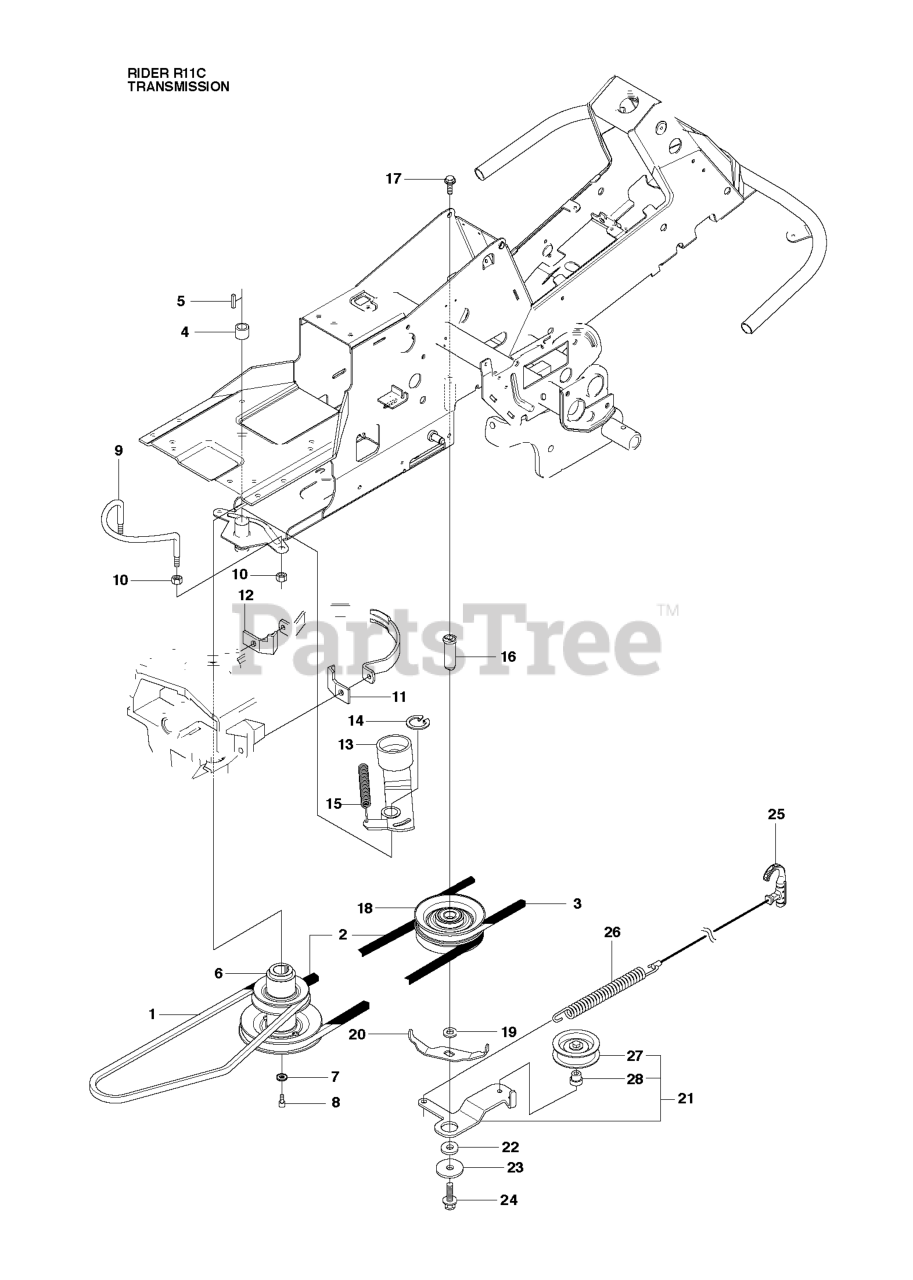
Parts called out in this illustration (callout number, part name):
6	Pulley Cpl
9	BELT GUIDE
10	NUT
11	Belt Guide Cpl., Right
12	Belt Guide Cpl.,Left
14	RETAINING RING SGA 25
16	SHAFT
20	BELT GUIDE
21	BELT TENSIONER ASSY
24	BOLT
27	PULLEY
